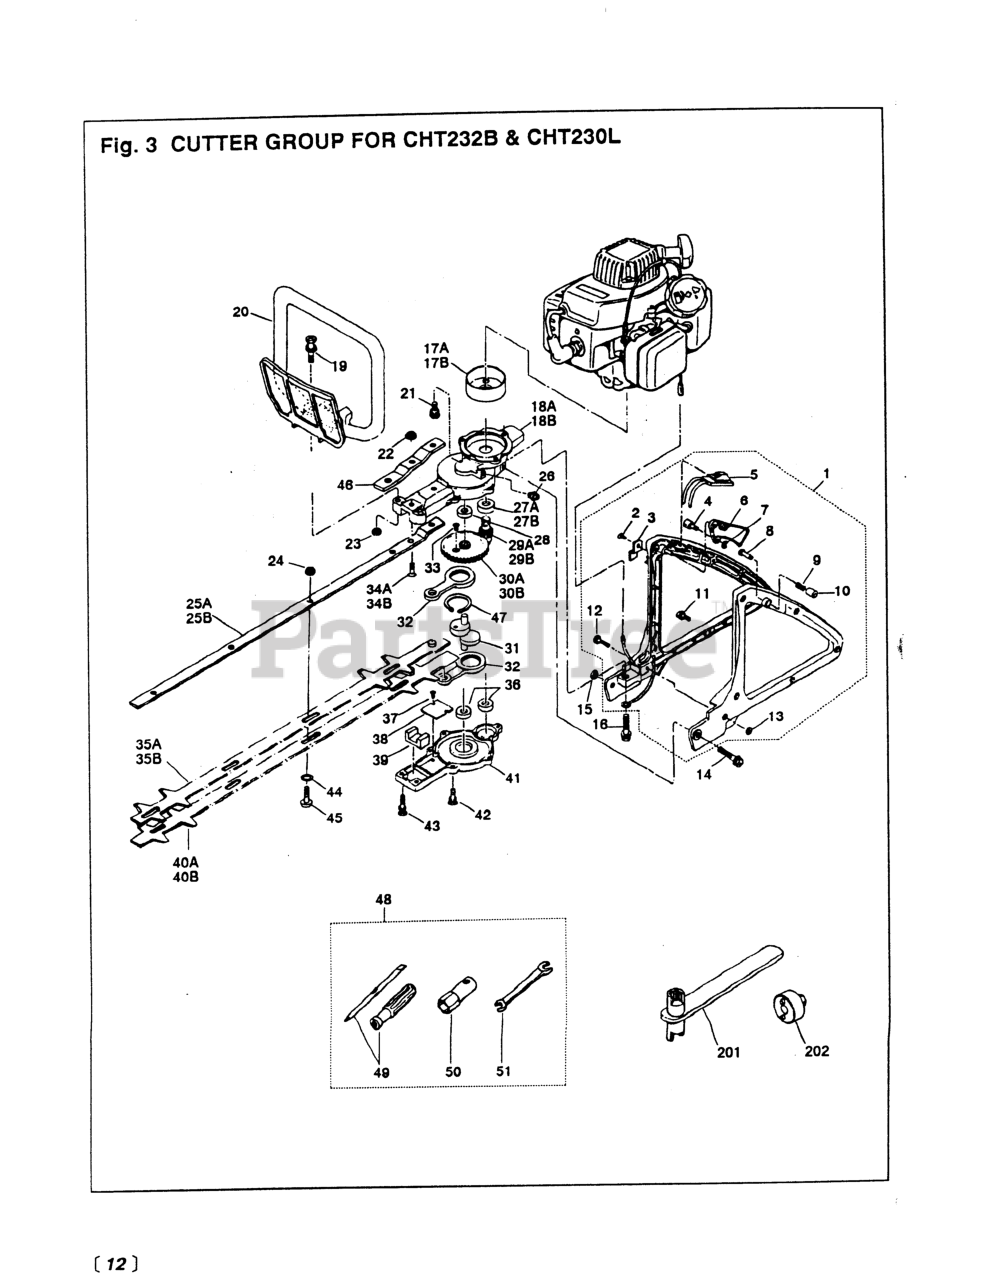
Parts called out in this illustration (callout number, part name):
2	SCREW, M4 x 10
3	PLATE
4	END, CABLE
5	SWITCH
7	RING, SNAP
9	SPRING
10	CAP, PIN
11	SCREW, M4 X 16
12	SCREW, M4 x 30
13	NUT, M6 X 4
14	BOLT, M6 X 50
15	NUT, M6 X 5
16	BOLT, M6 X 40
17B	DRUM, CLUTCH
18B	CASE, MIDDLE
21	BOLT, M6 X 14
22	NUT
23	NUT, M6 X 5
24	NUT, M6
26	FITTING, GREASE
27B	BEARING
28	BEARING
29B	PINION
30B	GEAR
31	CRANKSHAFT
32	ROD
33	SCREW
34B	SCREW
35B	BLADE, UPPER DOUBLE 30
36	BEARING
37	SCREW, M3 x 5
38	PLATE
39	FELT
40B	BLADE, LOWER DOUBLE 30
41	CASE, LOWER
42	BOLT, M5 x 16
43	BOLT, M5 X 20
46	PLATE (RPLS 3880-11130)
47	RING, SNAP, M25 X 1.2
48	TOOL SET
49	SCREWDRIVER
50	SOCKET, HEX, 3/4
51	SPANNER, 8 X 10 (RPLS 2540- )
202	WRENCH (TOOL)
